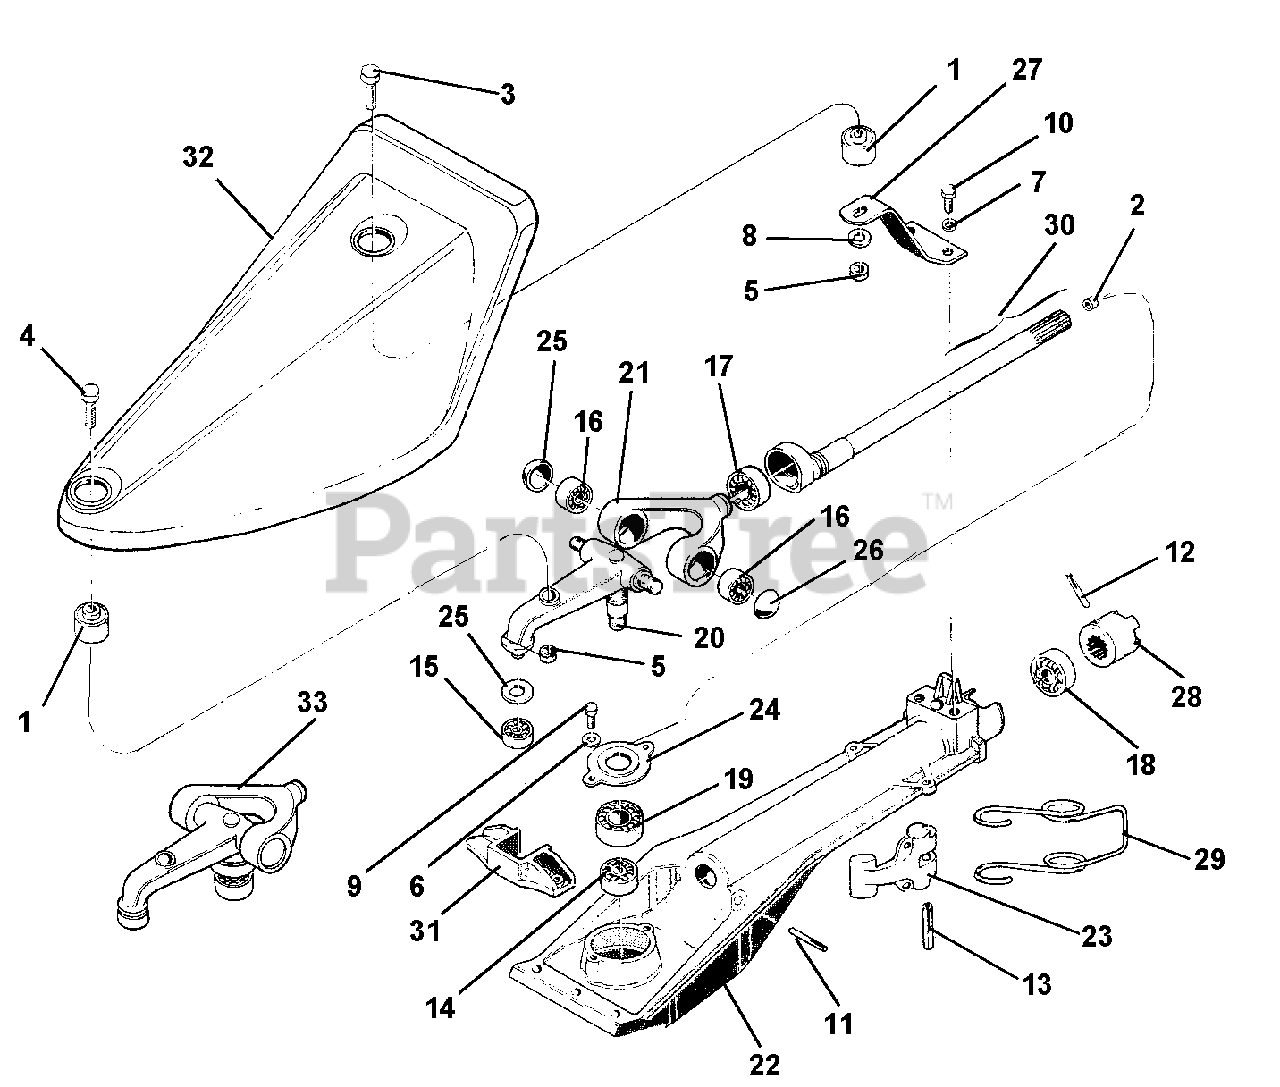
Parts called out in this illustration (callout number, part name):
3	SCREW M10 X 45
4	SCREW M10 X 60
5	NUT, SELF LOCKING M10
6	WASHER, LOCK 6.4
7	WASHER, LOCK 8.4
8	WASHER, LOCK 10.5
9	SCREW M6 X 12
10	SCREW M8 X 15
11	PIN, LOCKING 5 X 40
12	PIN, LOCKING 6 X 40
13	SPIRAL PIN 8 X 40
14	BEARING 12 X 37 X 12 6301
15	BEARING 62200-2RS 10 X 30 X 14
17	BEARING SKF 17 X 40 X 12 6203 ST
18	BEARING 20 X 42 X 12 6004 2RS
19	BEARING 20 X 47 X 14 6204-Z
20	BLADE CONTROL CRANK
22	CUTTER BAR SUPPORT
24	BEARING COVER
25	PROTECTION WASHER
26	CLOSING DISC
27	ELASTIC CONNECTION
28	PTO COUPLING
30	SHAFT WITH BUSHING
31	NYLON COUPLING
33	CRANK COMPLETE
